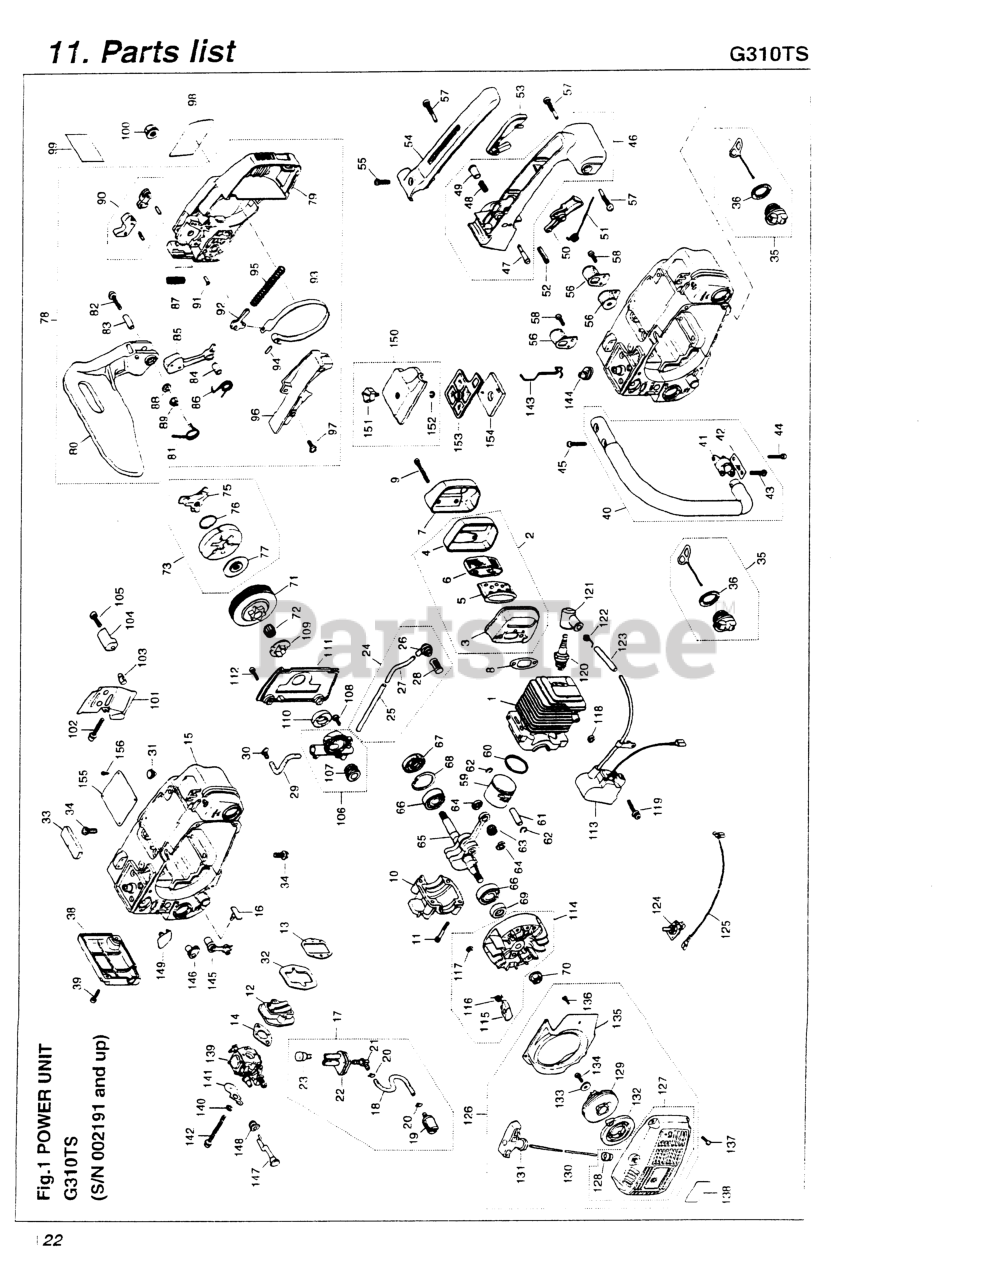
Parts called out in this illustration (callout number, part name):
1	CYLINDER
2	MUFFLER ASS
4	COVER
5	BAFFLE
6	ARRESTER
8	GASKET
10	CRANKCASE
11	BOLT, M5 X 30
12	VALVE ASSEMBLY
18	PIPE (USE -85411)
19	5500-85400 (RRLS. 1750-85300)
20	CLIP (REPLACES 2841-31280)
22	GROMMET
23	BREATHER ASSY (RPLS 2630-31270
24	PIPE ASSEMBLY
25	PIPE (USE -85411)
26	GROMMET (RPLS -31320)
29	PIPE (USE -85411)
30	PIN
31	VALVE A
32	SEAL
34	SCREW
36	GASKET
37	STOPPER
38	COVER (RPLS -31912)
39	SCREW
40	HANDLE, FRONT (RPLS -32102)
41	JOINT (RPLS -32120)
42	STOPPER (RPLS -32150)
46	HANDLE, REAR (RPLS -33101)
47	STOPPER
49	KNOB
50	LEVER, THROTTLE (RPLS -33310)
51	SPRING
55	SCREW
56	JOINT (RPLS -33510)
58	SCREW (REPLACES 50030272)
59	PISTON
60	RING
61	PIN, PISTON
62	RING, SNAP
63	BEARING
64	WASHER (RPLS 3310-41341)
65	CRANKSHAFT
67	SEAL, OIL
68	RING, SNAP, M32 x 1.2
69	SEAL, OIL (RPLS 1100-21210)
71	DRUM (RPLS 2631-51111)
72	BEARING
74	SHOE
76	SPRING
77	BOSS (A)
78	BRAKE ASSY (RPLS -54003)
79	COVER, CHAIN (RPLACES -53114)
82	SCREW
84	SPACER (RPLS -54210)
88	WASHER, M5 X .8
89	NUT (B)
90	LEVER, BRAKE COMPLETE
92	ARM, SLIDE
93	BAND
94	PIN
95	SPRING, BRAKE (RPLS. 50030121)
96	COVER SPRING
97	SCREW (REPLACES 50030272)
98	LABEL (RPLS-53120)
100	NUT
103	NUT
104	CATCHER, CHAIN (RPLS. -53411)
106	OIL PUMP ASSY (RPLS -55102)
107	GEAR
109	PLATE
110	SEAL
111	COVER, PUMP (RPLS -55311)
112	SCREW
114	ROTOR (RPLS -71200)
115	PAWL (RPLS -71220)
116	SPRING (RPLS -71230)
117	RING, SNAP, M4
119	BOLT
121	CAP
122	SPRING
124	SWITCH ASSEMBLY
126	STARTER ASSEMBLY
128	GUIDE (RPLS -75120)
129	REEL (RPLS -75211 & -75210)
131	KNOB (RPLS -75420)
132	HOLDER COMPLETE
136	SCREW (REPLACES 50030272)
137	SCREW
139	CARBURETOR ASSY (RPLS -81000)
141	PLATE, CHOKE
144	GROMMET
145	GROMMET A
146	GROMMET(B)
147	ROD (RPLS -82310)
148	GROMMET
149	CAP
152	RING, SNAP, M4
155	LABEL (RPLS -31410)
